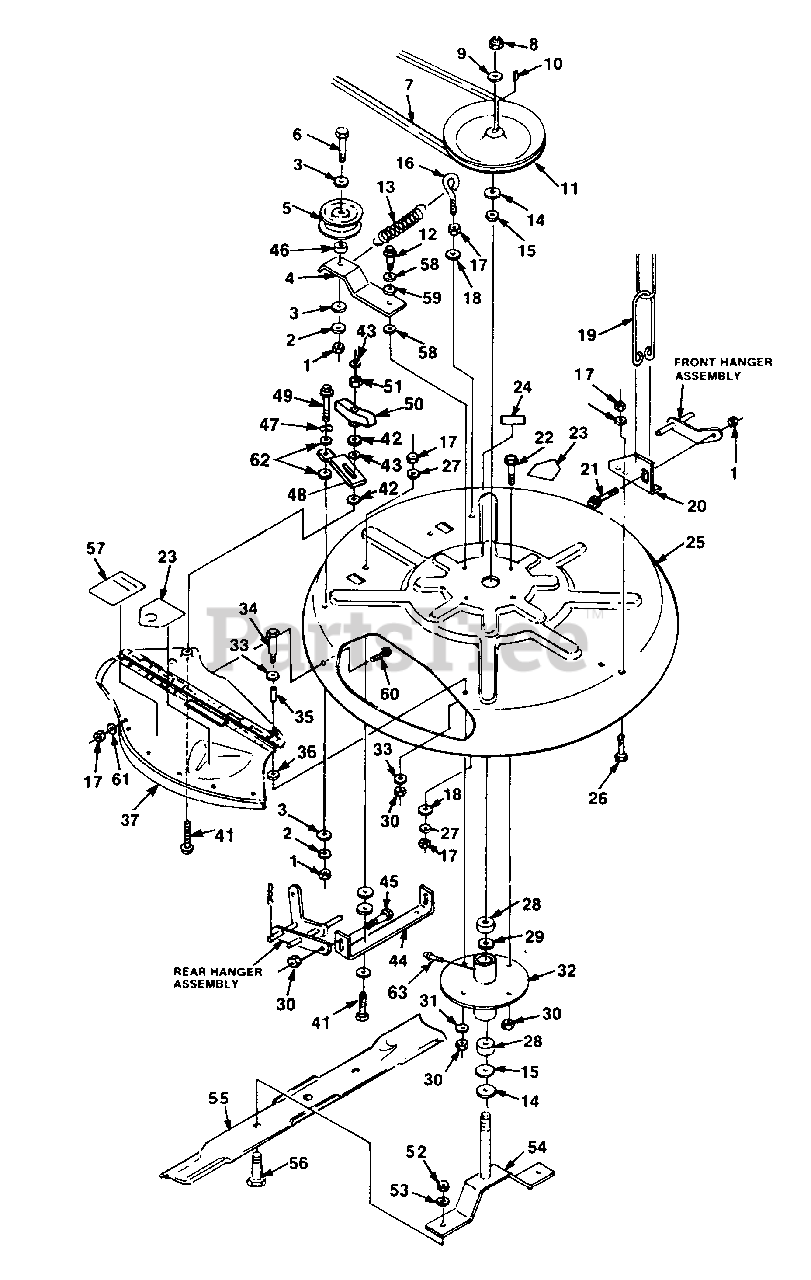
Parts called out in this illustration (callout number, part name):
1	NUT-Hex centerlock 3/8-16
2	WASHER- Lock 3/8
3	WASHER- Flat 7/16
4	ARM- Pivot
5	PULLEY- Idler
8	NUT- Hex locking
9	WASHER- Flat 13/16
10	KEY- 3/16 x 1.00
11	PULLEY- Spindle
12	SCREW- Cap hex hd 5/16-18 x 1.250
13	SPRING- Extension
14	SPACER-.100 Thick
15	WASHER-.036 Thick
16	BOLT- Eye
17	NUT- Centerlock 1/4-20
18	WASHER- Flat 114
19	LINK- Lower front lift
20	BRACKET- Front lift
21	BOLT- Shoulder 3/8-16 x 2.125
22	SCREW- Cap hex hd 5/16-18 x.750
23	DECAL- CPSC Warning
24	DECAL- No step
25	DECK- Cutter 30"
26	SCREW- Cap hex hd. 1/4-20 x.625
27	WASHER- Lock 1/4
28	BEARING- Cutter shaft
29	SPACER- Bearing
30	NUT- Hex centerlock 5/16-18
31	WASHER- Lock 5/16
32	SPINDLE HOUSING
33	WASHER- 5/16 SAE
36	WASHER- Flat 3/8
37	PLATE COVER ASSEMBLY
41	SCREW- Cap hex hd 1/4-20 x.750
42	WASHER- Plain
44	BRACKET- Rear lift
45	BOLT- Shoulder 5/16 x 18
47	WASHER- Spring
48	ARM- Pivot
49	BOLT- Hex hd cap 1/4-20 x.625
51	NUT- Hex 1/4-20 hvy
52	NUT- Hex centerlock 1/2-13
53	WASHER- Lock 1/2
54	SPINDLE & ADAPTER
55	BLADE
56	SCREW- Cap hex hd 1/2-13 x 1.25
57	DECAL- Danger
58	WASHER- Idler arm
59	SPACER- Idler arm
60	SCREW- 1/4-20 x 1"
61	WASHER- Flat 1/4
62	WASHER- Flat
